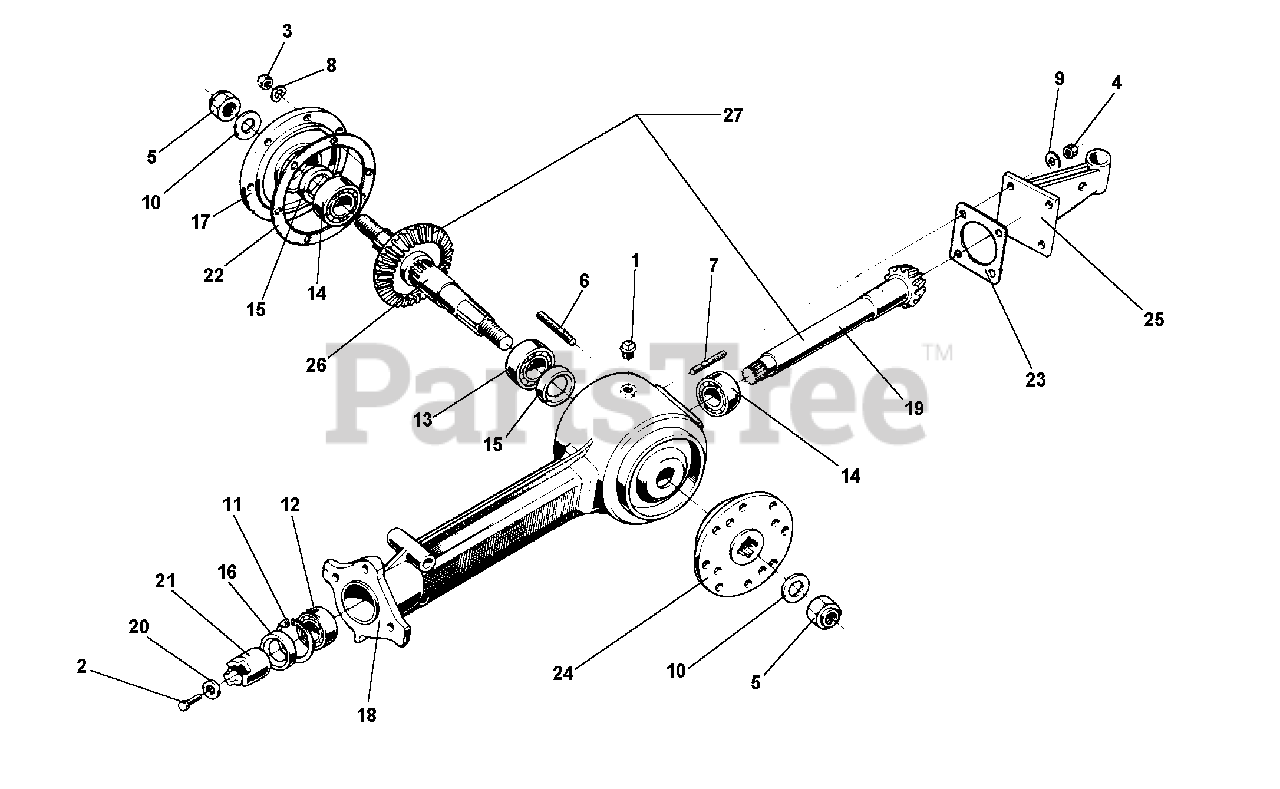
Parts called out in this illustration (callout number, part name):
2	SCREW M6 X 20
4	NUT, SELF LOCKING
5	NUT, SELF LOCKING M18 X 1.5
6	STUD M8 X 38 X 16 X 16
7	STUD M10 X 37 X 19 X 15
8	SUPER WASHER 8
9	SUPER WASHER 10
10	SUPER WASHER 18
11	CIRCLIP, INTERNAL D 52
12	BEARING 25 X 52 X 15
13	BEARING 30 X 62 X 16
14	BEARING 30 X 62 X 16
15	OIL SEAL 30 X 52 X 10
16	OIL SEAL 40 X 52 X 7
18	ROTARY HOE CENTRAL ASSEMBLY
19	ROTARY HOE PINION
20	WASHER 7 X 25 X 4
21	ROTARY HOE COUPLING
22	COVER GASKET
23	COVER GASKET
24	BLADE HOLDER FLANGE
26	SHAFT WITH GEAR
27	BEVEL GEAR PAIR
28	GEARBOX COMPLETE
